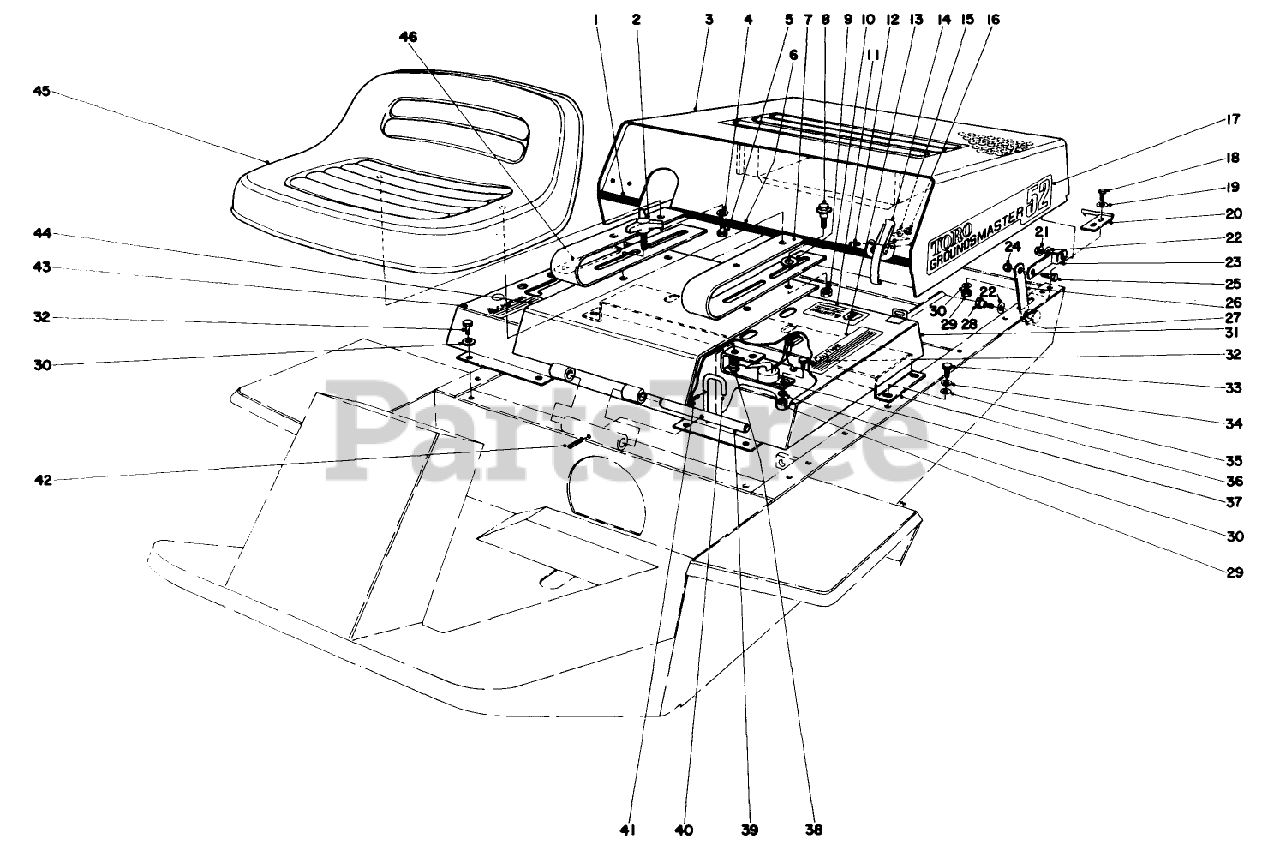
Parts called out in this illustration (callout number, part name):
1	HOOD TRIM
2	KNOB-SEAT
3	Hood
4	WASHER-LOCK
5	SCREW-HH
6	TRIM-HOOD
7	Seat Spring
8	BOLT-SHOULDER
9	WASHER-FLAT
10	NUT-LOCK, NI
11	DECAL-REFUELING
12	SCREW-PPH
13	Decal Caution
14	HOOK TYPE CLAMP
15	WASHER-LOCK
16	NUT-HEX
17	Decal-Groundsmaster
18	SCREW-HH
19	WASHER-FLAT
20	PivotPin L.H.
21	NUT-HF
22	WASHER-SPRING
23	Link Hood
24	NUT-HEX
25	SCREW-HH
26	Tie Hood
27	WASHER-FLAT
28	SCREW-SHOULDER
29	NUT-HEX
30	WASHER-LOCK
31	Cover-Seat Support
32	SCREW-HH
33	SCREW-HH
34	WASHER-LOCK
35	WASHER-FLAT
36	Seat Support
37	Seat Switch
38	SPRING
39	SHAFT-PIVOT, SEAT
40	Pin Seat Switch
41	PIN-SPRING
42	PIN-ROLL, SLOTTED
43	Decal Hydraulic Lift
44	Seat Mount
46	Decal Caution
